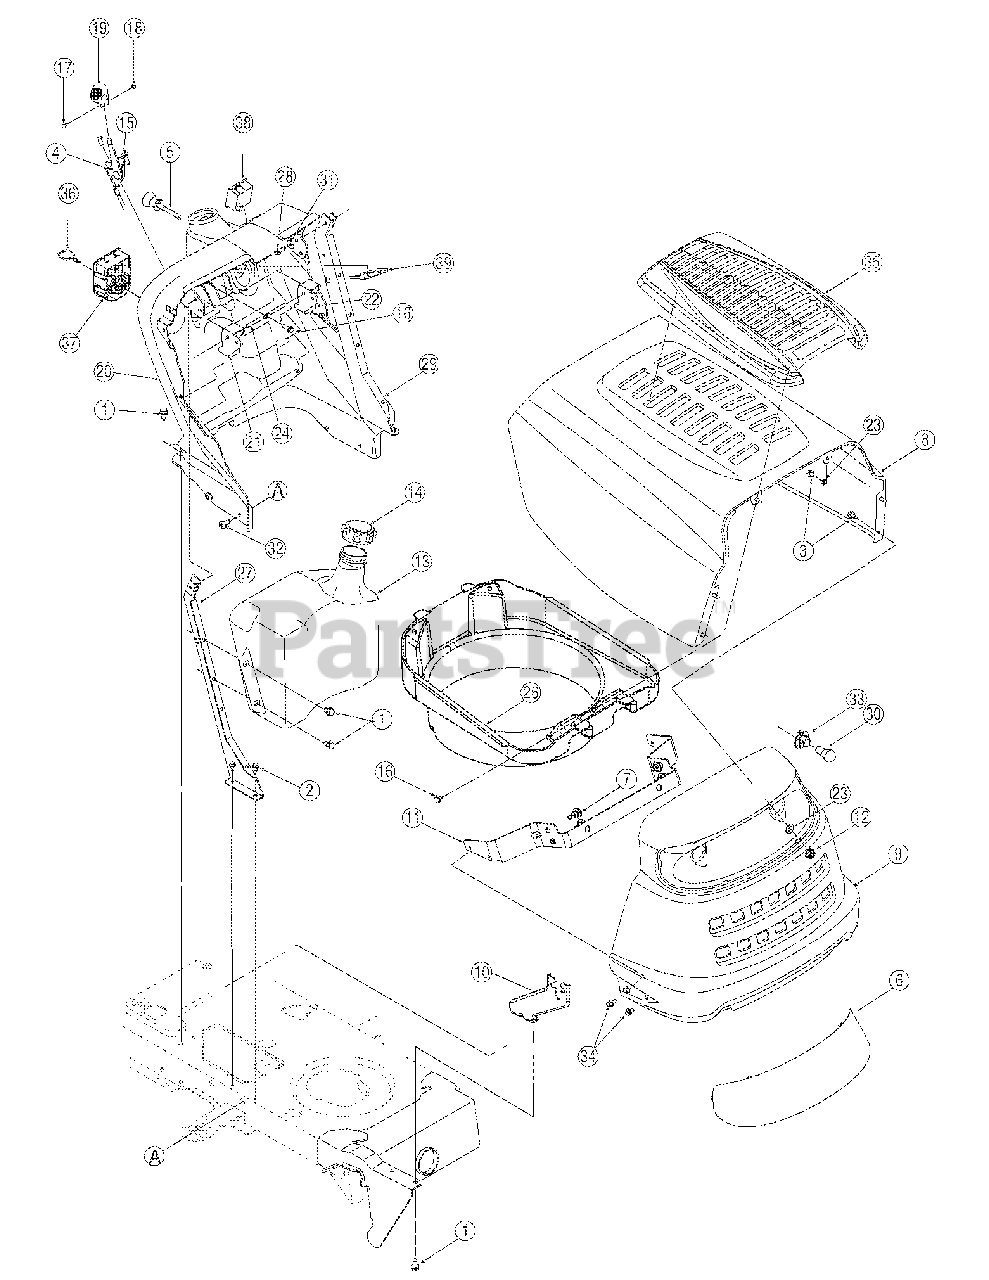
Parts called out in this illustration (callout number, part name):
1	Screw, 5/16-12 x.750
2	Self-tapping Screw, 1/4-20 x.5
3	Hex Cap Screw, 1/4-20 x.62
4	Throttle Control
4	Throttle/Choke Control
5	Choke Control
5	Choke Plug
6	Headlight Lens
7	Shoulder Screw,.43 x.29
13	Fuel Tank, Three Gallon
13	Fuel Tank, Two Gallon
14	Fuel Cap
15	Screw, 1/4-14 x.625
16	Self-tapping Screw, 1/4-15 x.75
17	Truss Phillips Screw, #8-32 x.375
18	Hex Nut, #8-32
19	Throttle Control Knob
20	Dash Panel (Electric PTO)
20	Dash Panel (Manual PTO)
21	Cruise Control Button
22	Parking Brake Button
23	Flat Washer, .265 x .938
24	Brake/Cruise Pivot Rod
26	Hood Plenum
30	Lamp
31	Bell Washer,.265 x.75 x.062
32	Screw, 5/16-18 x.75
33	Headlight Socket
34	Hex Index Screw, 1/4-20 x.625
35	Hood Cover
36	Ignition Key w/ plastic cover
36	Ignition Key w/o plastic cover
37	Ignition Switch
38	Systems Ind. Monitor w/ Hr Meter
39	Electric PTO Switch
